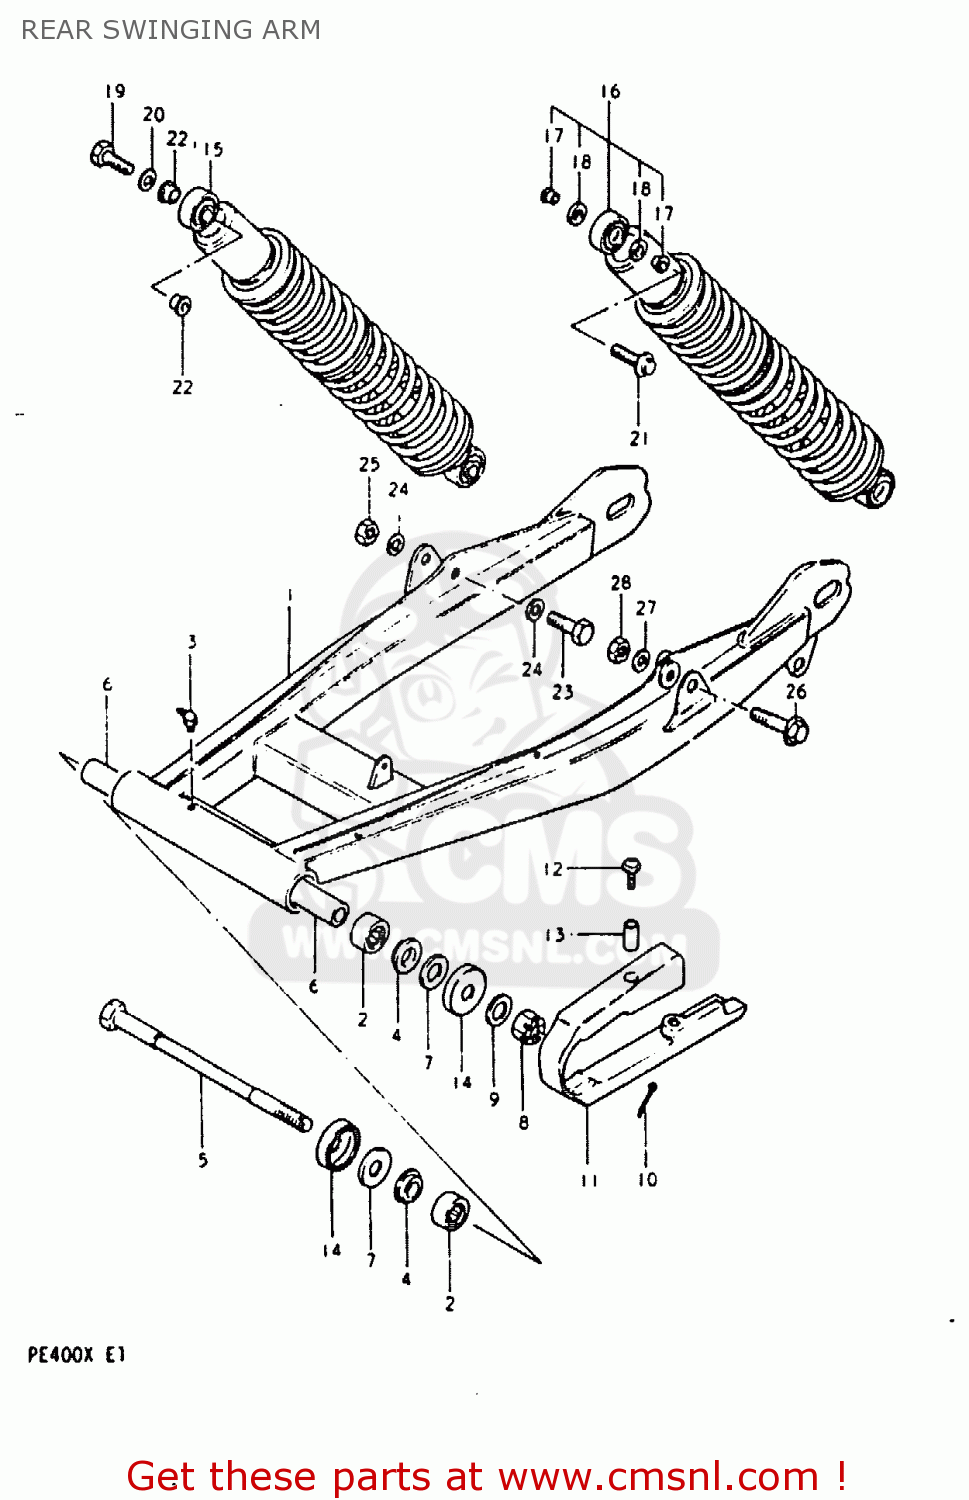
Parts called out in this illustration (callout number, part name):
1	SWING ARM ASSEMBLY,REAR
2	BEARING
3	NIPPLE,GREASE
4	BUSHING,REAR SWING ARM PIVOT
5	SHAFT,REAR SWING ARM
6	SPACER,REAR SWING ARM
7	WASHER
8	NUT 14MM
9	WASHER
10	COTTER PIN
11	BUFFER,CHAIN TOUCH DEFLECTOR
12	SCREW,CHAIN TOUCH DEFEND
13	SPACER (5.5X8X4)
14	COVER,RR SWGARM DUST SEAL
15	ABSORBER ASSEMBLY,REAR SHOCK
16	ABSORBER ASSEMBLY,REAR SHOCK
17	SPACER,REAR SHOCK ABSORBER
18	DUST SEAL,REAR SHOCK
19	BOLT
20	WASHER
21	BOLT 10X40
22	SPACER,RR SHK ABS INNER
23	BOLT(8X46)
24	WASHER
25	NUT
26	BOLT(10X52)
27	WASHER
28	NUT
